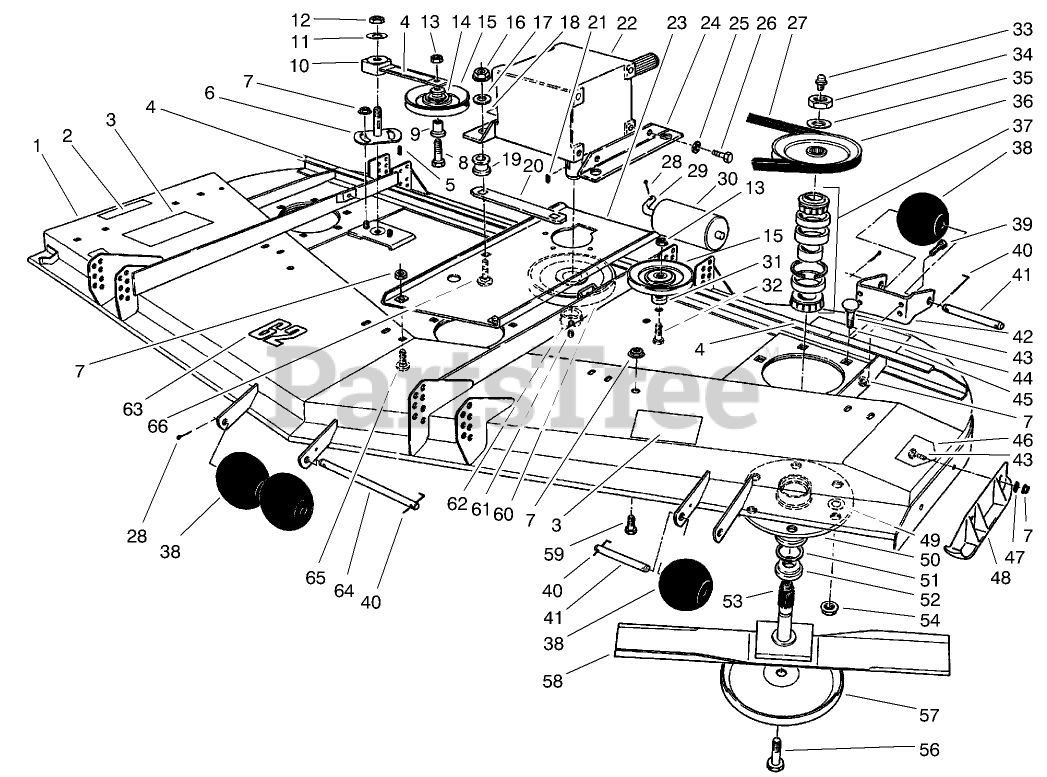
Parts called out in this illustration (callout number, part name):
1	Cutting Deck (Incl. Ref. #2-4, 44-46 & 63)
1	Cutting Deck (Europe) (Incl. Ref. #2-4, 44-46 & 63)
2	DECAL-DANGER
2	DECAL-WARNING, DEFLECTOR
3	DECAL-DANGER, THROWN OBJECT
3	DECAL-DANGER
4	DECAL-DANGER
5	KEY-SQUARE
6	PLATE-IDLER
7	NUT-HHF, WHIZ
8	SCREW-HH
9	BUSHING-PULLEY
10	IDLER ARM ASM
11	WASHER-FLAT
12	NUT-LOCK, NI
13	NUT-HEX
14	WASHER-FLAT
15	PULLEY-IDLER
16	NUT-LOCK, SIDE
17	WASHER
18	DECAL-OIL
18	DECAL-LUBE
19	MOUNT
20	Cover-Gear Box
21	KEY-WOODRUFF
22	Gearbox
23	Base-Gearbox
24	Bracket-Gearbox
25	WASHER-LOCK
26	SCREW-HH
27	V-BELT
28	PIN-COTTER
29	SHAFT-ROLLER, REAR
30	ROLLER-DECK
31	SPACER
32	SCREW-HH
33	FITTING-GREASE
34	NUT-HEX
35	WASHER
36	PULLEY AND HUB ASM
37	BEARING ASM
38	ROLLER
39	SCREW-HH
40	PIN-SPECIAL
41	SHAFT-ROLLER
42	Bracket-Roller
43	SCREW-CARR
44	DECAL-TORQUE
44	DECAL-TORQUE, BLADE BOLT
45	DECAL - WARNING
46	DECAL-DANGER
46	DECAL-DANGER, INT'L
47	LOCKWASHER-PYRAMID
48	Skid
49	WASHER-FLAT
50	HOUSING-SPINDLE
51	SEAL-OIL
52	SPACER
53	SHAFT
54	NUT-HF
56	BOLT-BLADE
57	CUP-SCALP, ANTI
58	Blade
59	SCREW-HH
60	PULLEY
61	SCREW-SET, HSH
62	BUSHING-LOCK, TAPER
63	DECAL
64	SHAFT-ROLLER
65	SCREW-CARR
66	SCREW-CARR
